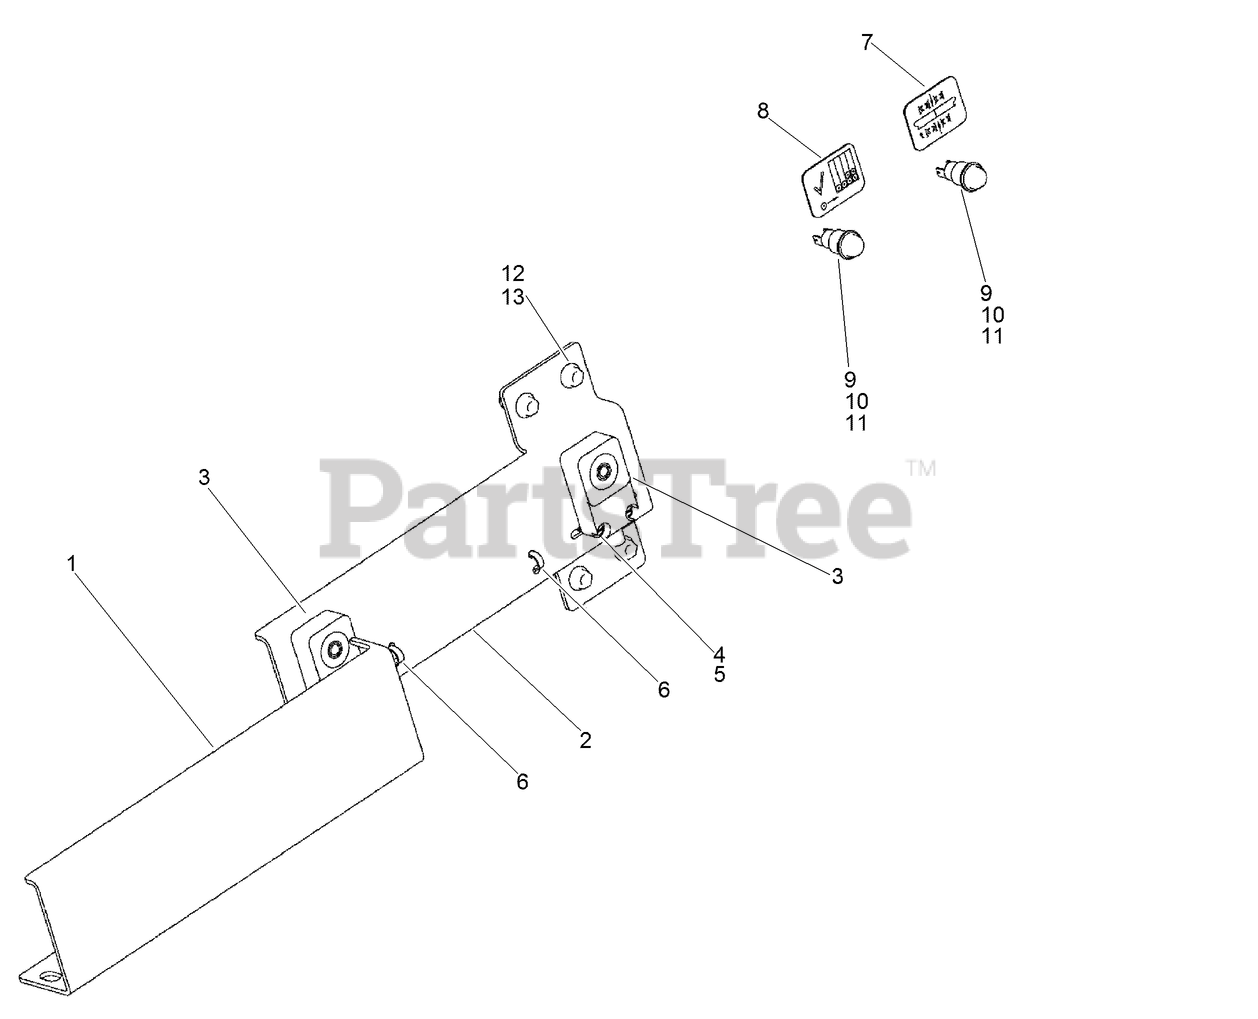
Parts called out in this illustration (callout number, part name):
1	PLATE - Sensor Flag
2	PLATE - Switch Mount
3	SWITCH-PROXIMITY
4	SCREW - Phd Sltd #10-24 x 1.00 CST ZND
5	NUT-#10-24 KEPS
6	STRAP-TIE
7	DECAL - Pipe Breakout Clear
8	DECAL - Pipe Return Clear
9	TYPE T-2 SOCKET ASM
10	BULB-TYPE T-2, 12VOLT
11	LENS-DOME, FLUTED GREEN (TYPE T2)
12	SCREW-HH
13	NUT-TORQUE, PREVAILING
